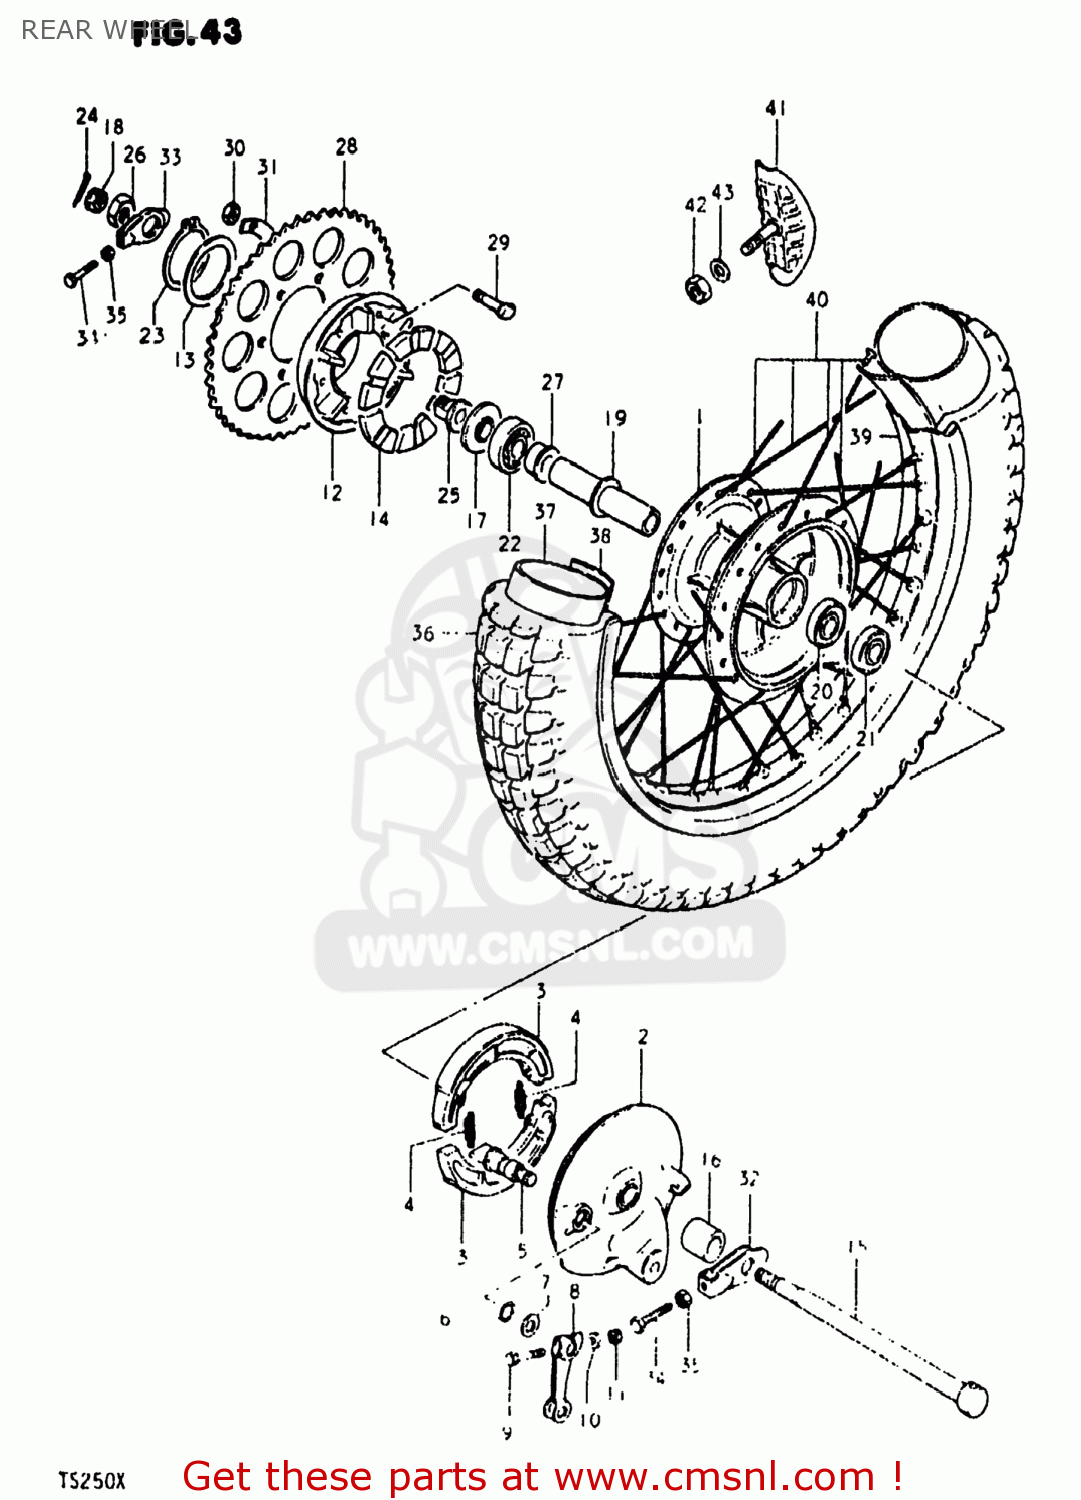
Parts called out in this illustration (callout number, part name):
1	DRUM,REAR HUB
2	PANEL,REAR HUB
3	SHOE,BRAKE (MCA)
4	SPRING
5	CAM,FRONT BRAKE
6	O-RING,BOSS
7	WASHER (15X24X1.6)
8	LEVER,RR BRAKE CAM
9	BOLT 6X40
10	WASHER
11	NUT
12	DRUM,REAR SPROCKET MOUNT
13	WASHER(62.5X77X1.6)
14	ABSORBER,RR WHEEL HUB SHOCK
15	AXLE,REAR
16	SPACER (15.2X26X20)
17	SPACER,REAR AXLE,RIGHT
18	NUT
19	SPACER,REAR HUB BEARING
20	BEARING, RH
21	OIL SEAL
22	BEARING
23	CIRCLIP
24	PIN 30X40
25	SPACER,REAR AXLE,LEFT
26	NUT
27	SPACER,REAR HUB BEARING
28	SPROCKET,REAR
29	BOLT(8X33.5)
30	NUT
31	WASHER
32	ADJUSTER,CHAIN,R
33	ADJUSTER,CHAIN,L
34	BOLT
35	NUT
36	TIRE
37	TUBE,INNER
38	PROTECTOR,WHEEL,INNER
39	RIM,REAR WHEEL (2.15X18)
40	SPOKE SET,RR
41	STOPPER,BEAD
42	NUT
43	WASHER
